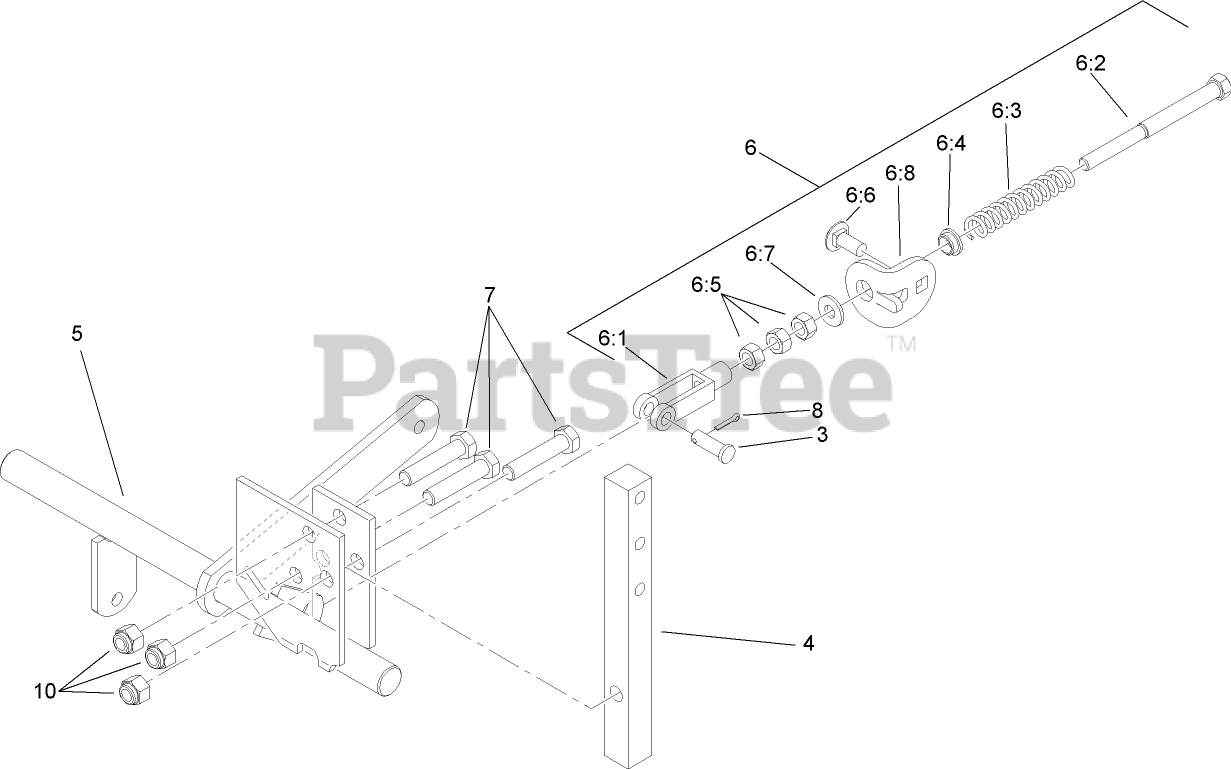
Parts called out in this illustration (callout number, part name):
3	PIN-CLEVIS
4	ARM-SHAFT, CONTROL
5	CONTROL-MOTION, LH
6	NEUTRAL RETURN ASM
6:1	YOKE-ADJUSTABLE
6:2	BOLT-RETURN, NEUTRAL
6:3	SPRING-RETURN, NEUTRAL
6:4	BUSHING-NYLON, FLANGED
6:5	NUT-HEX
6:6	SCREW-CARR
6:7	WASHER-FLAT
6:8	TAB-ADJUSTMENT
7	SCREW-HH
8	PIN-COTTER
10	NUT-LOCK, NI
